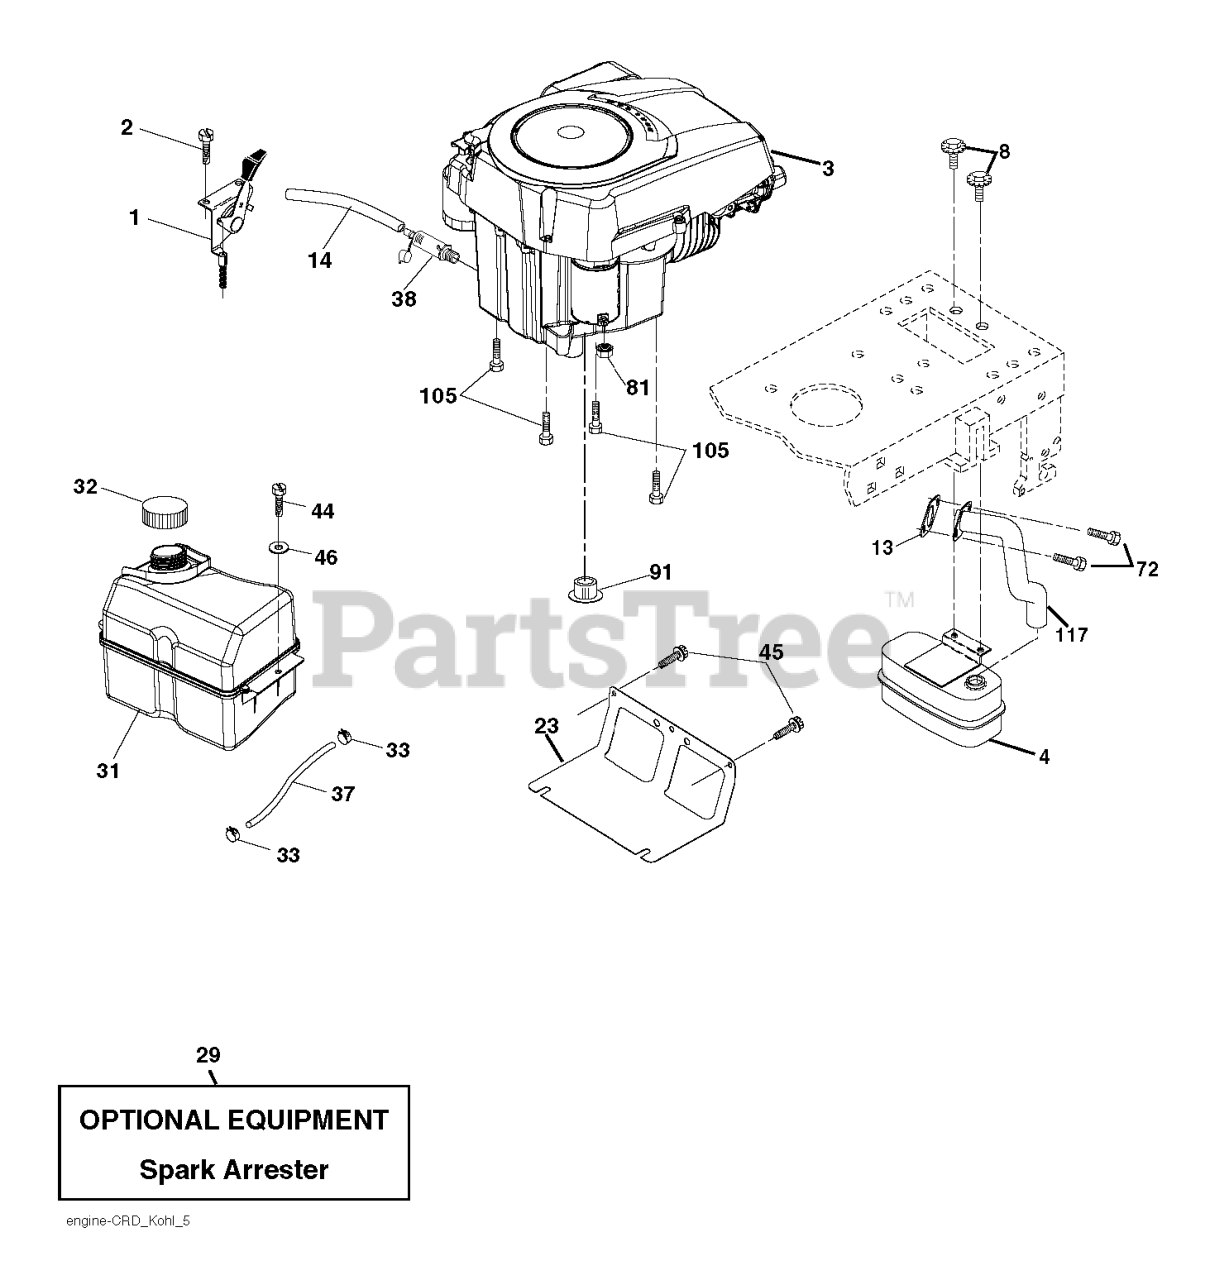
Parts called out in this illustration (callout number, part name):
1	CONTROL.TH/CK.C.
2	SCREW.#10 X 0.750.BOS
4	MUFFLER.SINGLE.CYL.KOHL/B&S
8	BOLT.5/16-18UNCX3/4 W/SEMS.BLK
13	GASKET.EXHAUST.KOHLER
14	TUBE, DRAIN OIL ASM.
23	SHIELD.BROWNING.DBR.GUARD
29	KIT.SPARK ARRESTOR 794945 B&S
31	RP TANK FUEL FRT 1.5 GAL
32	FUEL CAP
33	HOSE CLAMP
37	LINE.FUEL.20
38	PLUG DRAIN OIL EASY
44	SCREW HEXWSHR 1/4-20X3/4
45	SCREW, 3/8-16X3/4
72	SCREW.SOCKET HD.5/16-1
81	NUT
91	BUSHING.1.375OD
105	SCREW 3/8-16X1
117	RP.TUBE.EXHAUST.KOHL.COURAGE
